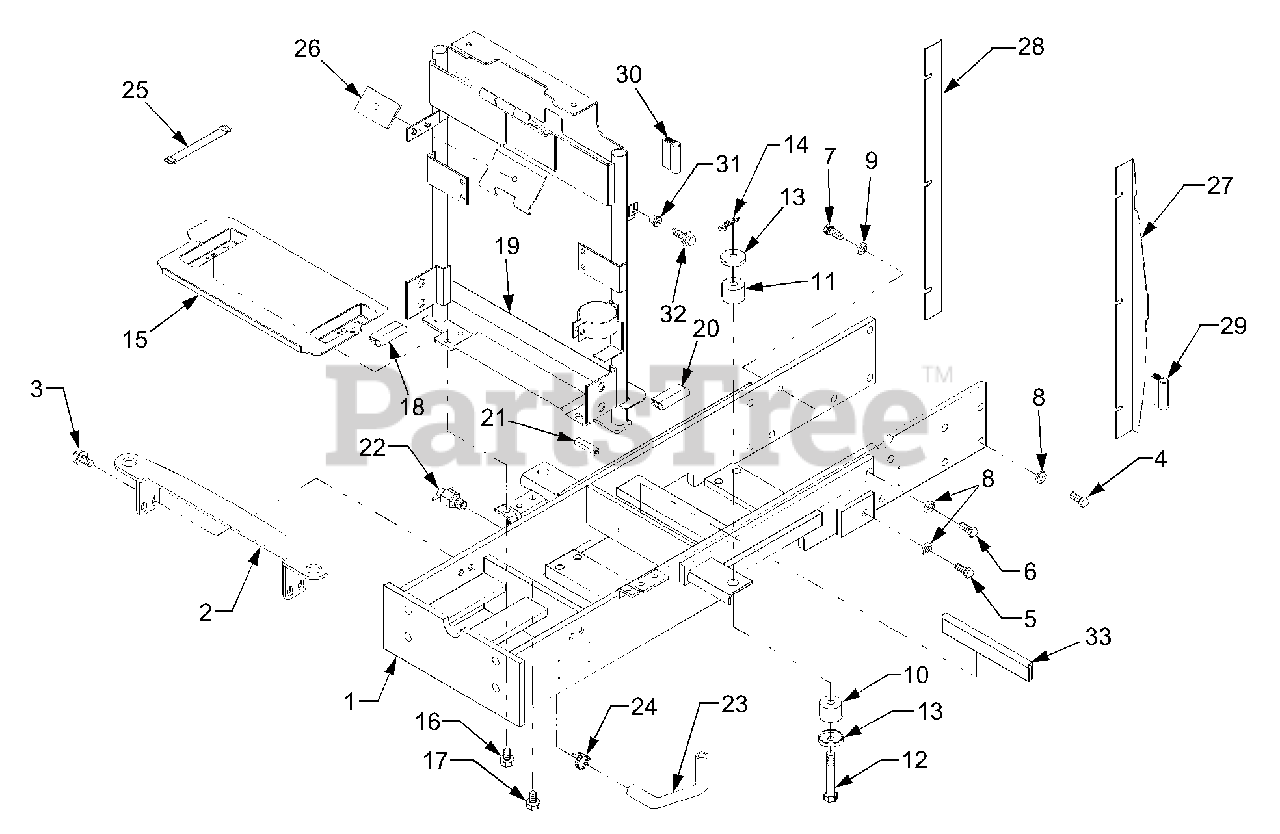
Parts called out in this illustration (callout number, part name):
1	Frame, Front Axle
4	Bolt
8	Washer, Spring
9	Washer, Spring
15	Support, Battery
19	Support, Aircleaner
22	Cock, Drain
25	Band, Aircleaner)
29	Rubber
31	Rubber, Cushion
